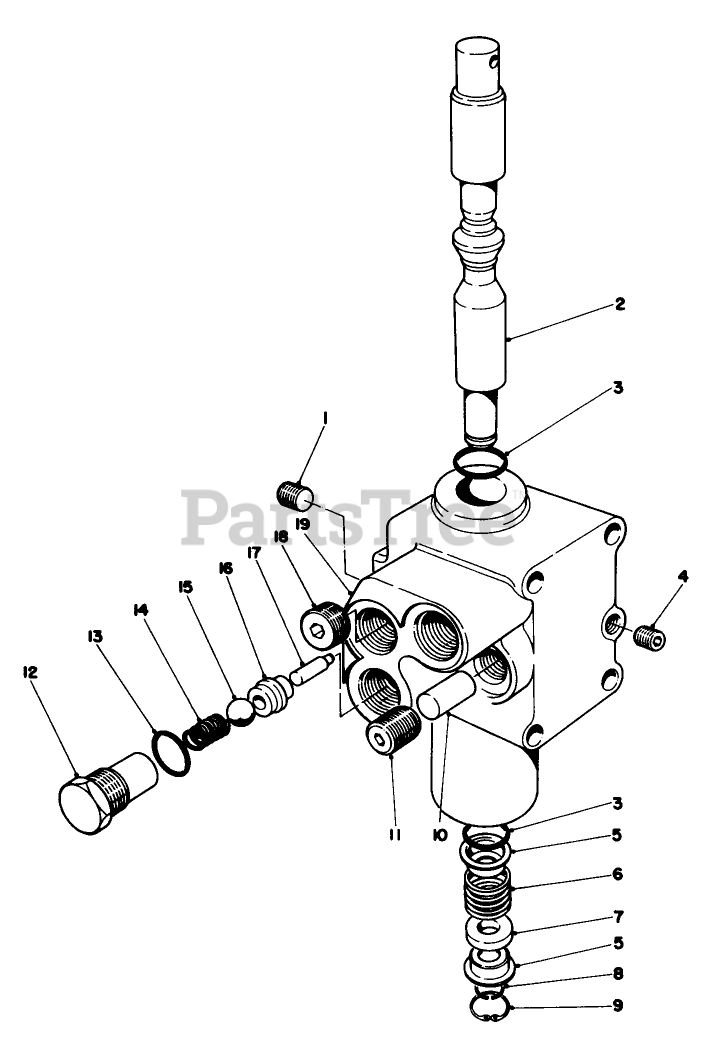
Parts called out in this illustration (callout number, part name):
2	SPOOL
3	O-RING
5	RETAINER
6	SPRING
7	FLOAT SPACER
8	RING-SNAP
9	RING-SNAP
13	O-RING
14	SPRING
16	SEAT-VALVE
